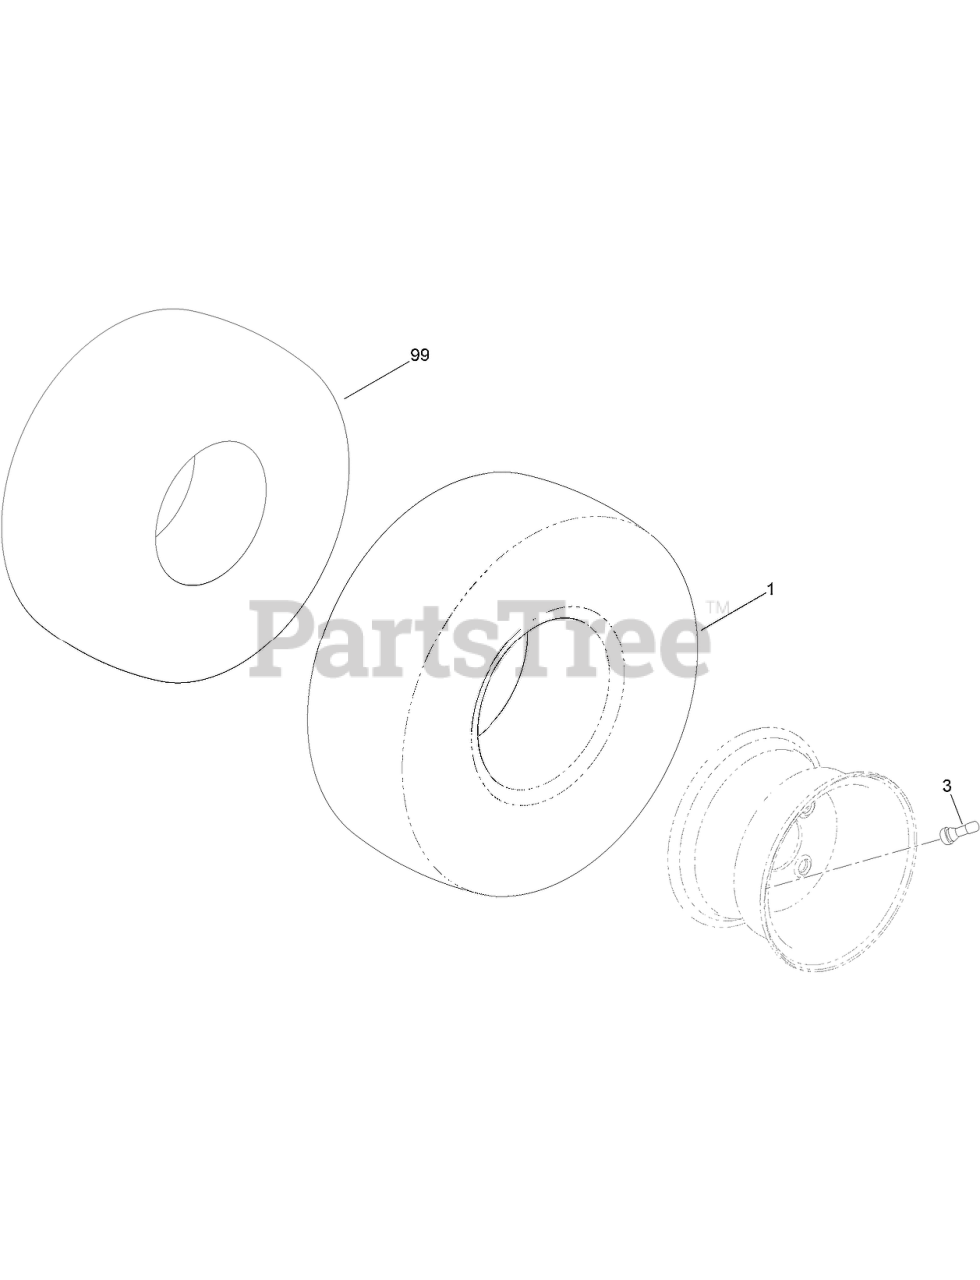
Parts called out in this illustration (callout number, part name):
1	TIRE-2 PLY
3	STEM-VALVE
99	TUBE-TIRE
